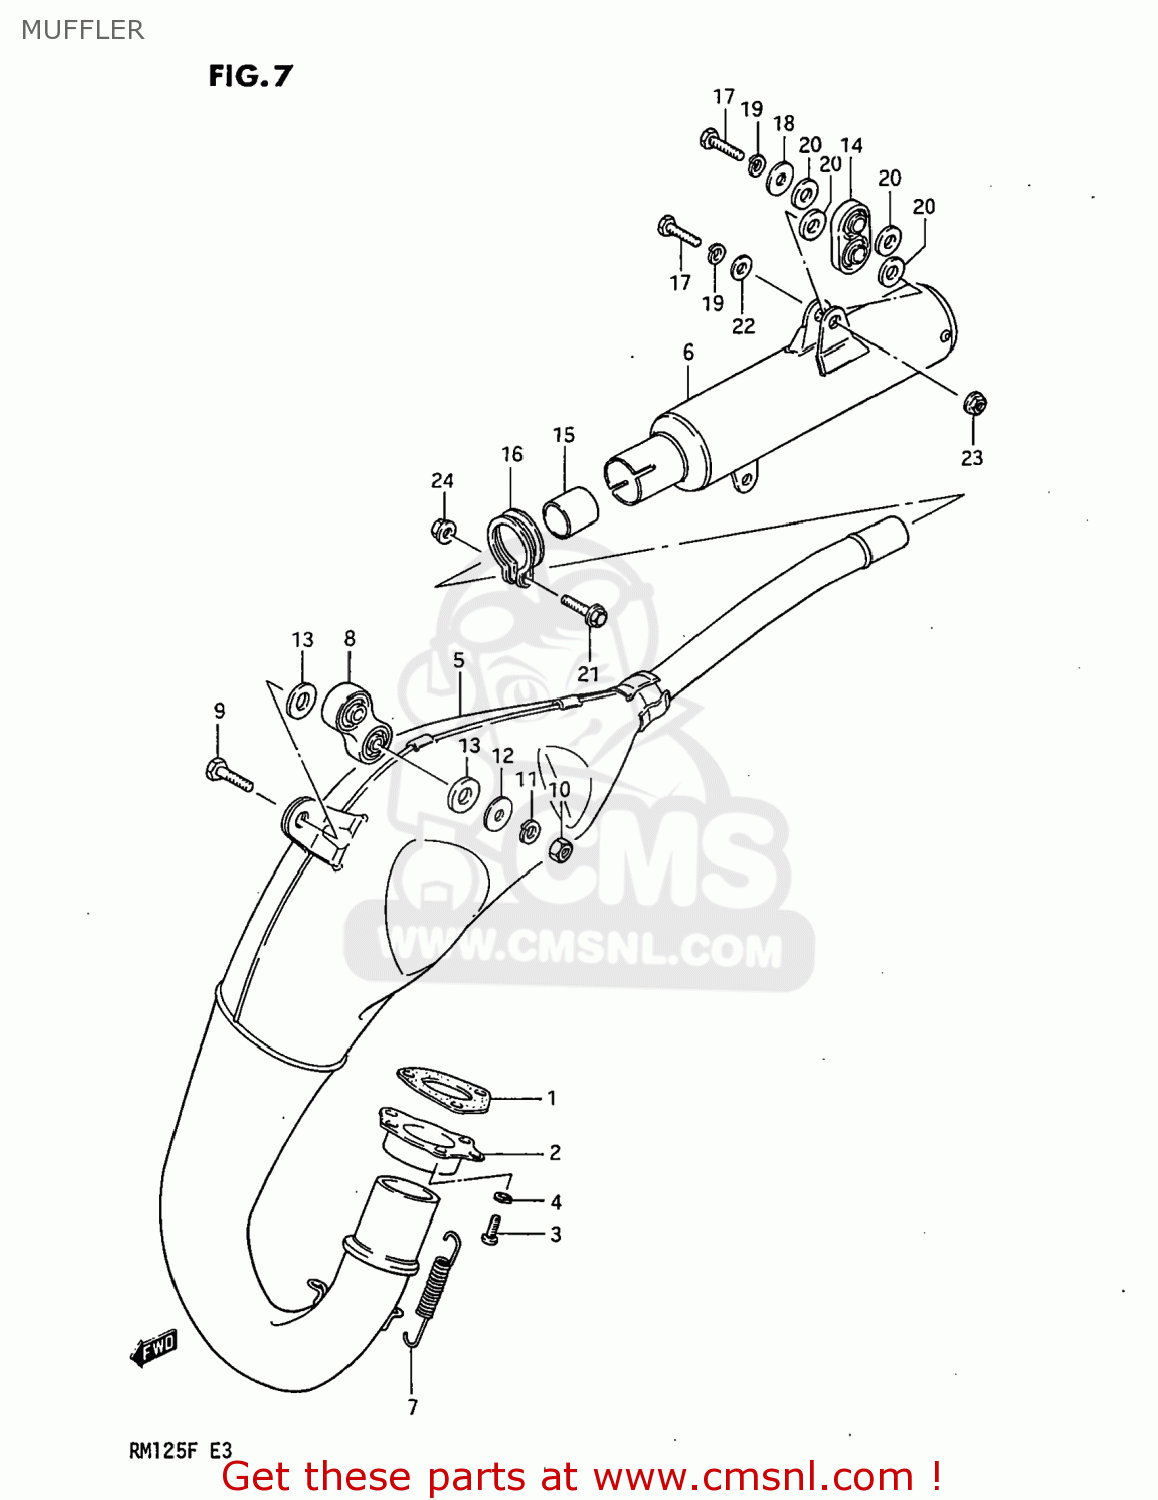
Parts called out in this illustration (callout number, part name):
1	GASKET,EXHAUST PIPE (MCA)
2	FLANGE,EXHAUST PIPE
3	SCREW
4	LOCK WASHER
5	BODY,MUFFLER
6	BODY,MUFFLER,SECOND
7	SPRING
8	DAMPER,MUFFLER
9	BOLT(8X32)
10	NUT 8MM
11	LOCK WASHER
12	WASHER
13	WASHER(13X28X1.6)
14	DAMPER,MUFFLER,SECOND
15	GASKET,SECOND MUFFLER (NAS)
16	CLAMP,MUFFLER SECOND
17	BOLT
18	WASHER
19	LOCK WASHER
20	WASHER(10.5X20X2.5)
21	BOLT
22	WASHER
23	NUT
24	NUT 6MM
